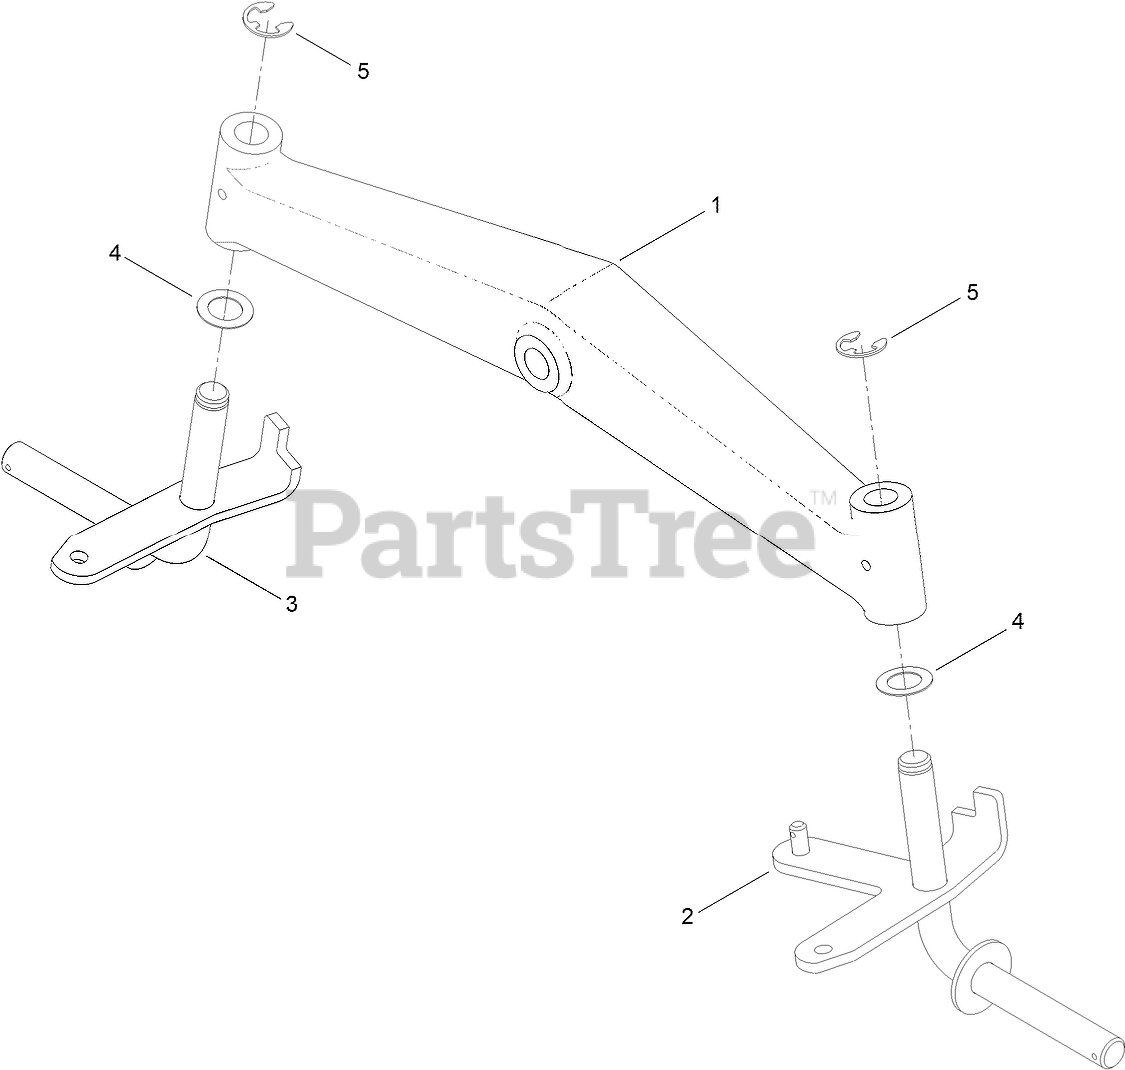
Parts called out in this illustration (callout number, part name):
1	AXLE-FRONT
2	SPINDLE-LH
3	SPINDLE-RH
4	WASHER-THRUST
5	E-RING
